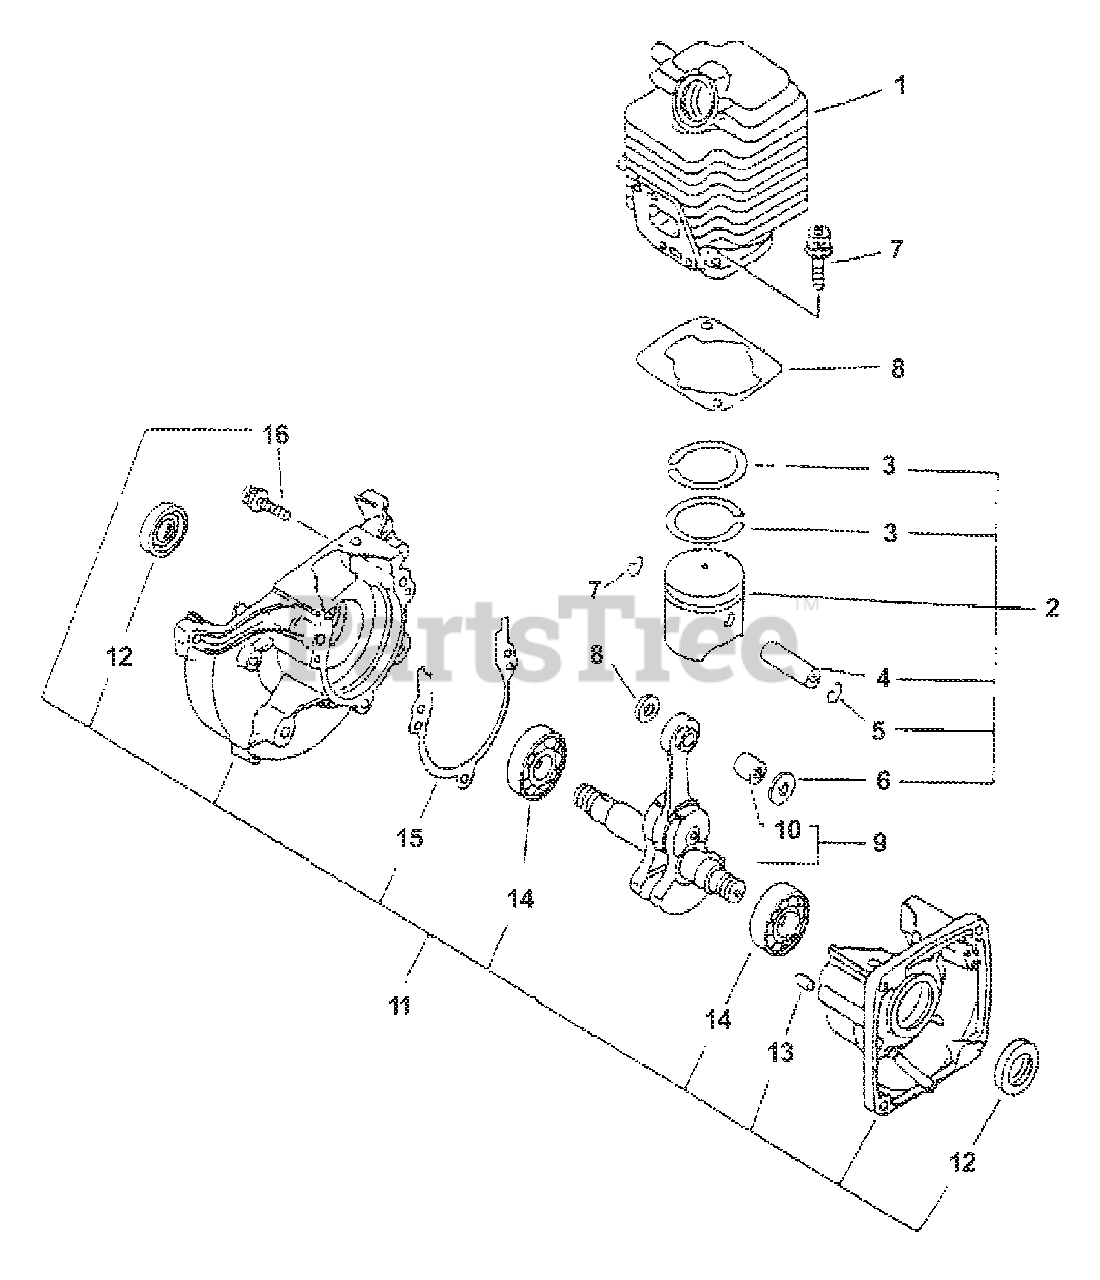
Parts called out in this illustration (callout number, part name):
1	CYLINDER
2	PISTON KIT
3	RING, PISTON
4	PIN, PISTON 8
5	RING, SNAP
6	WASHER, THRUST
7	BOLT 5×22
8	GASKET, CYLINDER
9	CRANKSHAFT ASSY
10	BEARING, NEEDLE
11	CRANKCASE KIT
12	SEAL, OIL 12
13	PIN, LOCATING 4
14	BEARING, BALL - 6201 C3
15	GASKET, CRANKCASE
16	BOLT 5×28
